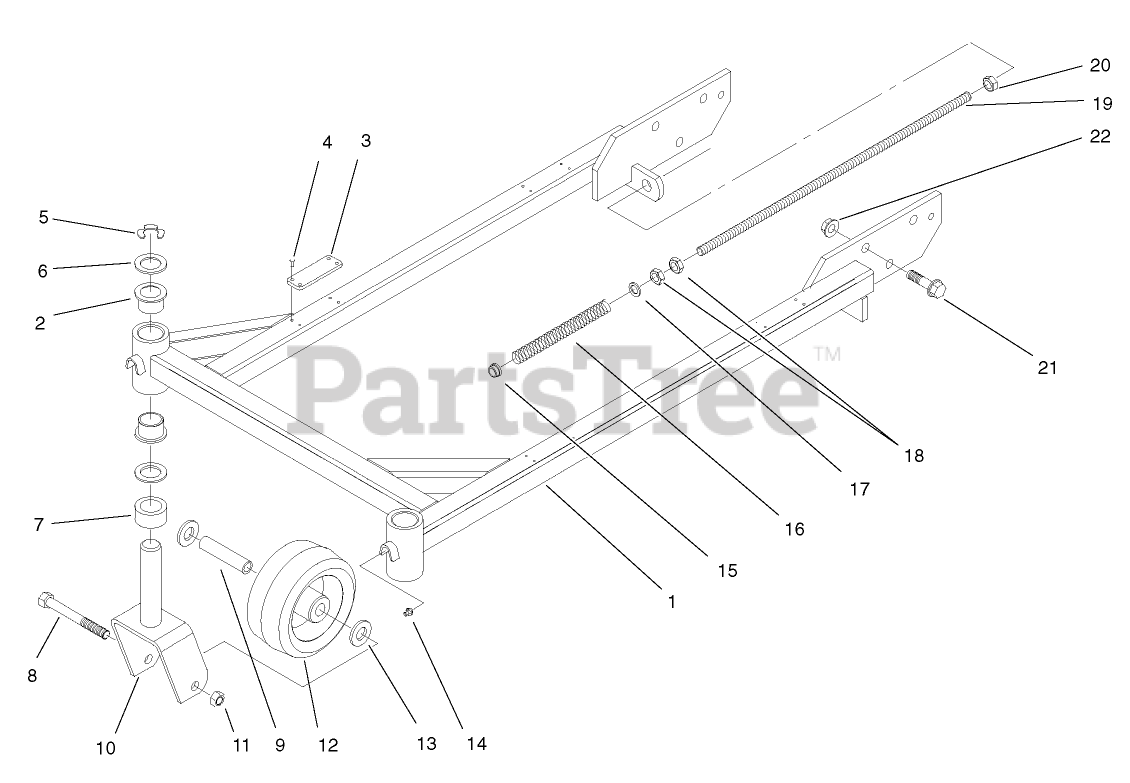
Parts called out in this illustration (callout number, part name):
1	Frame-Carrier
2	BUSHING
3	PAD-RUBBER
4	RIVET
5	RING-RETAINING
6	WASHER-THRUST
7	SPACER-CASTOR
8	SCREW-HH
9	SPANNER
10	FORK-CASTER ASM
11	NUT-HEX
12	CASTER WHEEL ASM
12:1	BEARING-OUTSIDE
12:2	BEARING-ROLLER
12:3	FITTING-LUBE, 45 DEG
13	SPACER-WHEEL
14	FITTING-GREASE
15	BUSHING-FLANGE
16	SPRING
17	WASHER
18	NUT-JAM
19	SHAFT-ADJUSTING
20	NUT-LOCK, NI
21	SCREW-HHF
22	NUT-HF
